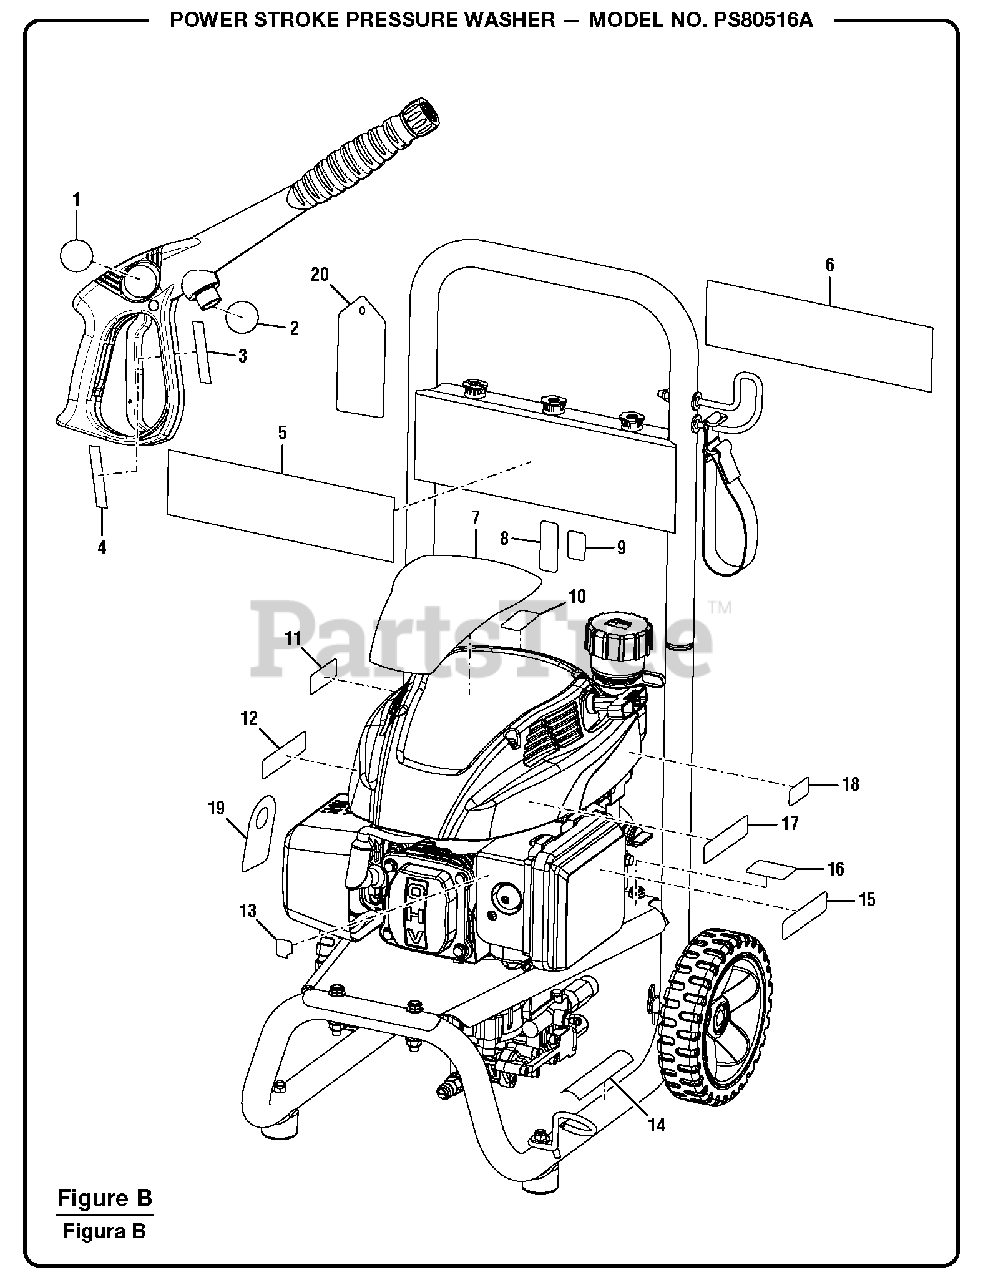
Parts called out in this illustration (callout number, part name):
1	Logo Label
2	Warning Label
3	Warning Label (Sp)
4	Wand Rating Label
5	Performance Label
6	Quick Start Label
7	Logo Label
8	E85 Label
9	No Oil Label
10	Add Oil Label
11	Lubricant Label
12	Hot Surface Label
13	Primer Bulb Label
14	Data Label
15	Inquiries Label
16	Danger Label
17	Combustion Warning Label
18	Run / Start Label
19	Add Oil Hangtag
20	Nozzle Hangtag
